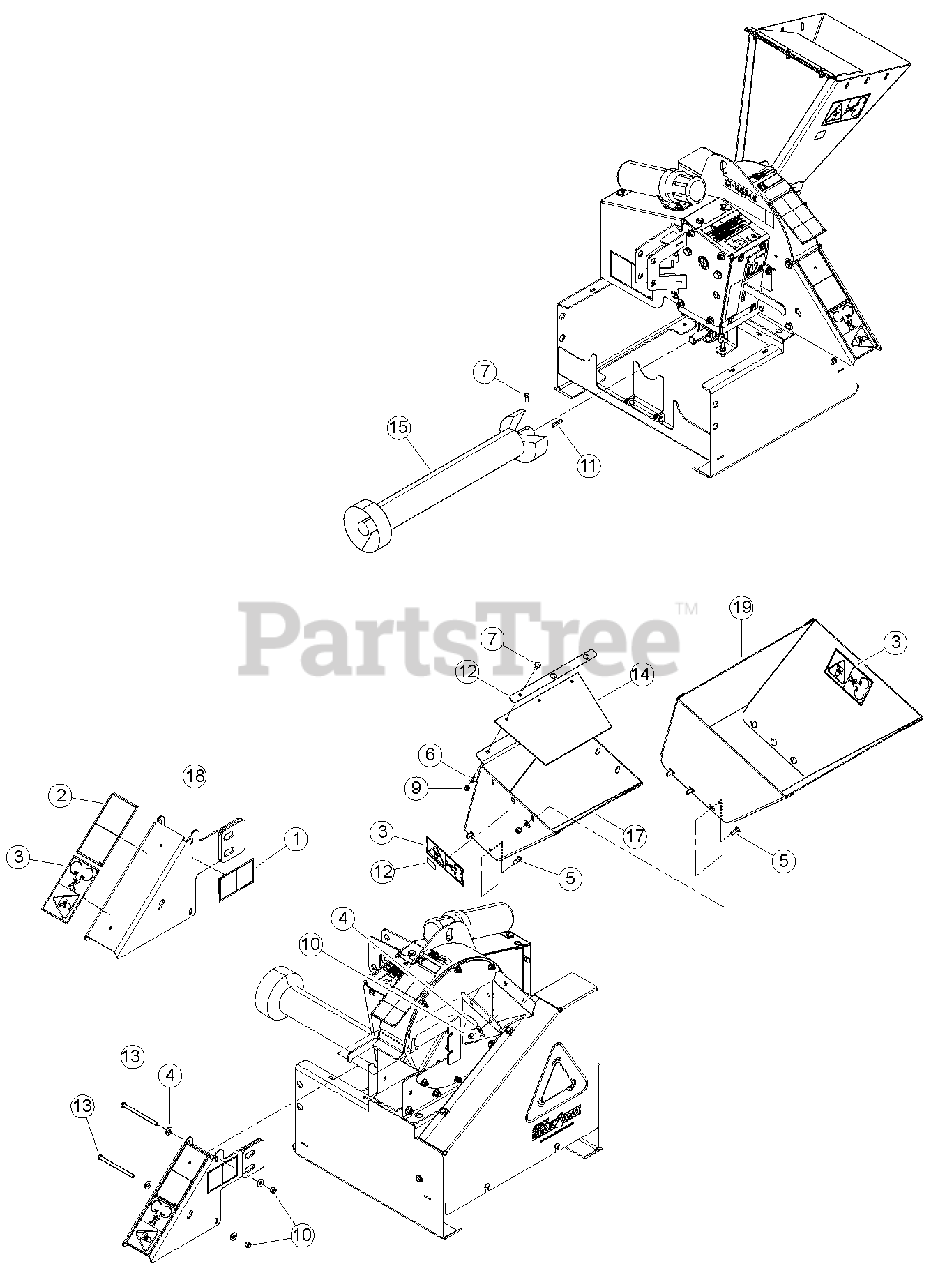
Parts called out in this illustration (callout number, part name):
1	DECAL, KNIFE ACCESS ISO
2	DECAL, DISCHARGE ISO
3	DECAL, BLADE DANGER ISO
5	BOLT, 3/8 X 1 CRG GR5 NC ZP
6	WASHER, 5/16 FLAT ZP
7	SCREW, 3/8 X 3/4 SQ HD SET ZP
8	BOLT, 5/16 X 1 CRG GR5 ZP
9	NUT, 5/16 NE NYLOCK ZP
11	KEY, 1/4 SQUARE X 1-1/2 LONG PLAIN
12	DECAL, CE APPROVAL
13	BOLT, 3/8 X 5-1/2 HEX HD GR5 ZP
14	FLAP, CHIPPER CHUTE
15	DRIVESHAFT, 540 C/S WS
16	STRIP, FLAP RETAINER
17	ASSEMBLY, HOPPER
18	ASSEMBLY, DISCHARGE CAP
19	ASSEMBLY, EURO CHUTE EXT.
